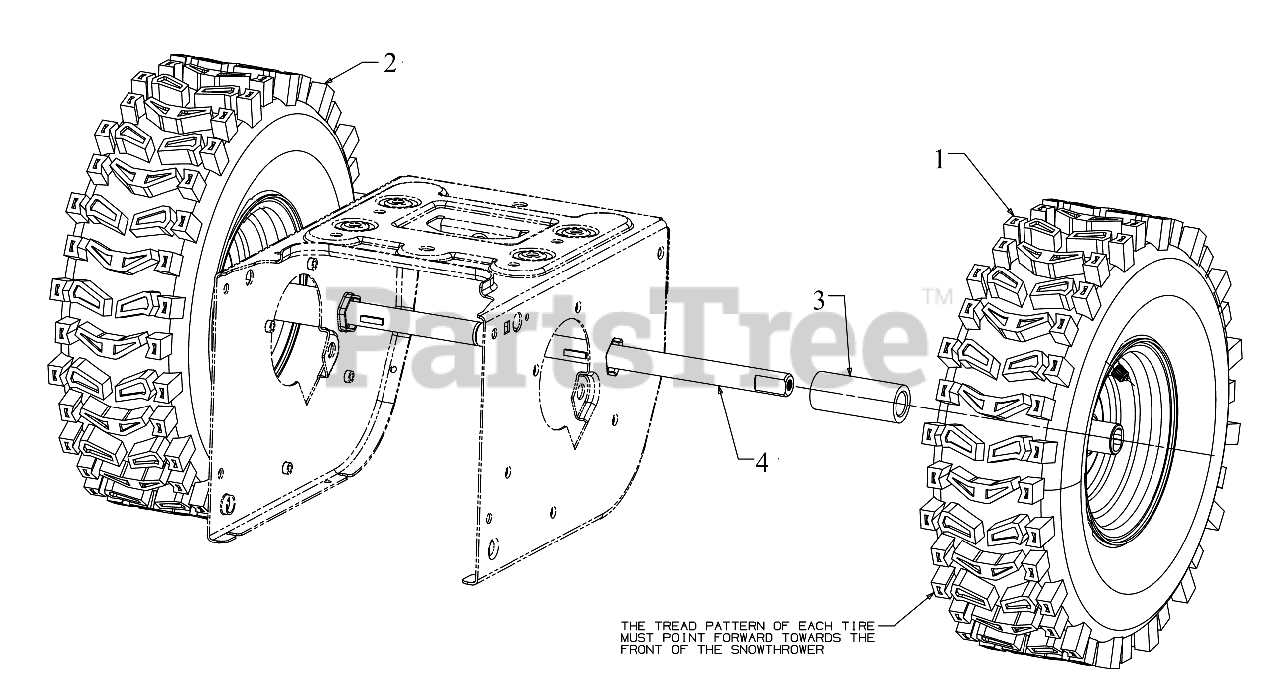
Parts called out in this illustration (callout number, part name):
1	TUBELESS VALVE
2	TUBELESS VALVE
3	WHEEL SPACER 1.25ODX.75X3.00
4	AXLE .75OD x 11.12LG
